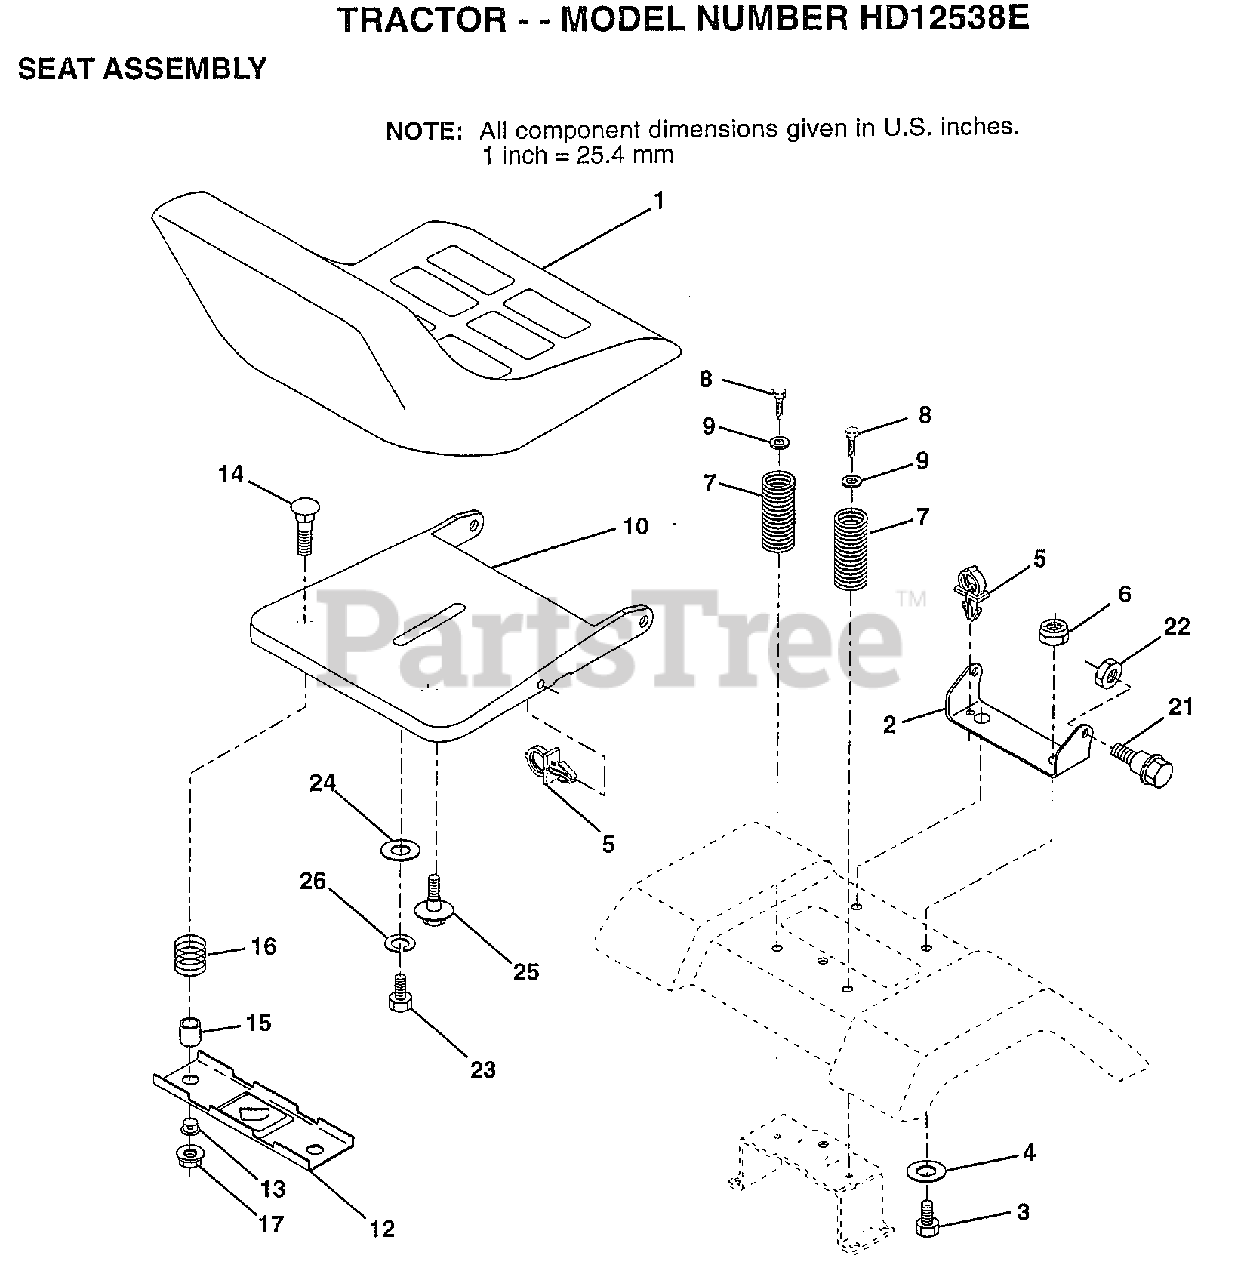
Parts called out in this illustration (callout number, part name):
2	BRACKET PVT SEAT
3	BOLT
4	WASHER PM
5	CLIP.PUSH-IN.HING
6	NUT
7	SPRING COMPRESSIO
8	SCREW GTV
9	WASHER
10	PAN-SEAT
12	BRKT SWITCH
13	BUSHING
14	BOLT-RD HD SQ NK
15	SPLIT SPACER
21	"BOLT,SHOULDER"
22	NUT
23	BOLT
24	WASHER
25	"BOLT,SHOULDER"
26	LOCKWASHER
